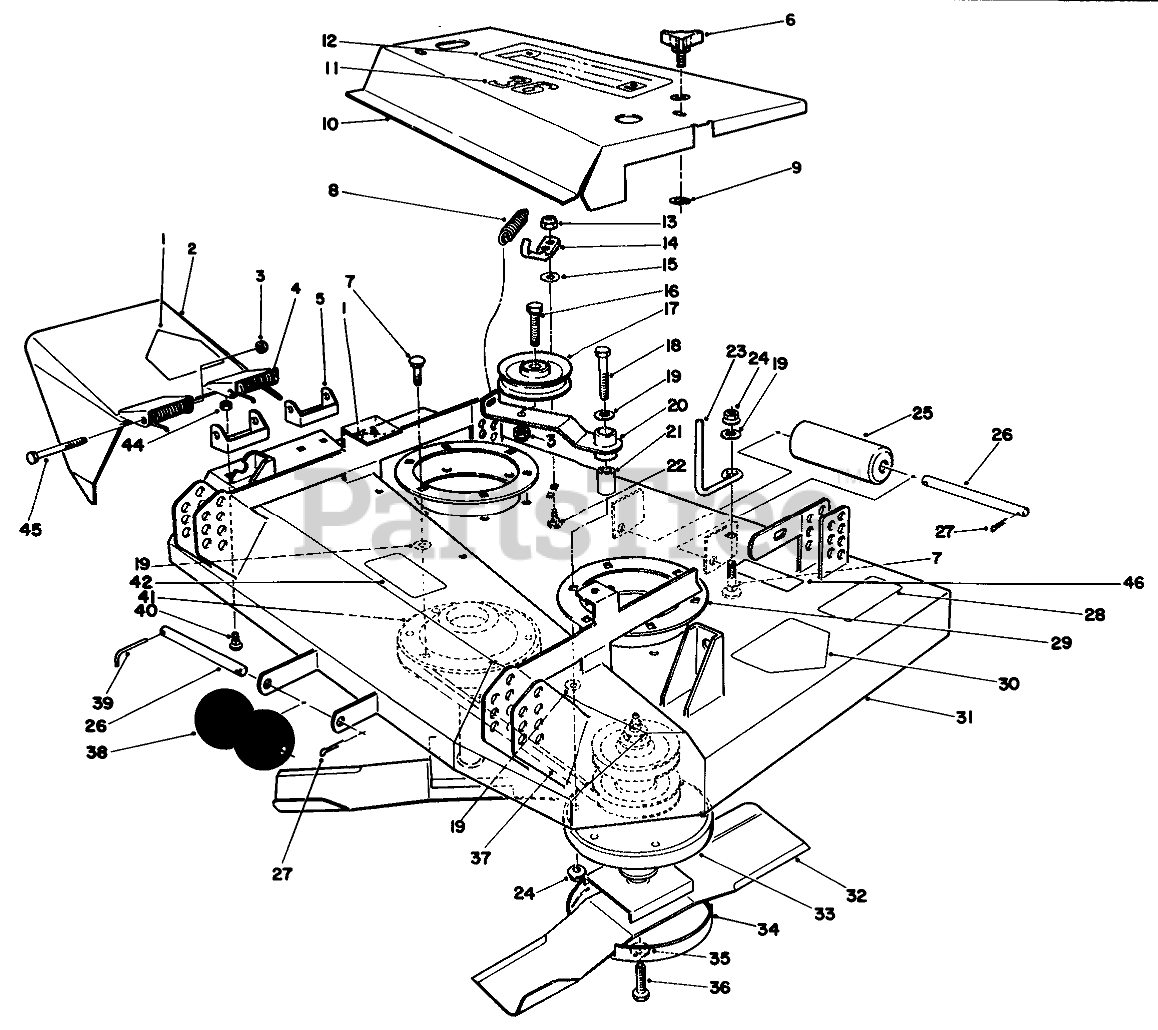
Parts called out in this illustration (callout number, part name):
1	DECAL-DANGER
2	Deflector-Grass (Incl. Ref. #1)
3	NUT-HEX
4	SPRING
5	Bracket-Pivot
7	SCREW-CARR
8	SPRING-EXTENSION
9	RING-RETAINING
10	Cover ASM
11	Decal-36 Inch
12	DECAL-PROLINE
13	NUT-LOCK, NI
14	ROD - SPRING
15	WASHER-FLAT
16	SCREW-HH
17	PULLEY-IDLER
18	SCREW-HH
19	WASHER-FLAT
20	Wa-Arm
21	SLEEVE-PIVOT, IDLER
22	SCREW-CARR
23	ROD-BELT
24	NUT-HF
25	ROLLER-DECK
26	SHAFT-ROLLER
27	PIN-COTTER
28	DECAL-TORQUE
29	SUPPORT-DECK, RING
30	DECAL-DANGER
31	Deck Assembly (Incl. Ref. #28, 30, 42 & 46)
32	BLADE-SAIL, EXTRA HIGH
33	HOUSING - SPINDLE ASM
34	CUP-SCALP, ANTI
35	WASHER-LOCK
36	SCREW-BLADE
37	V-BELT-DRIVE, DECK
38	ROLLER
39	PIN-SPECIAL
40	SCREW-CARR
41	SPINDLE ASM
42	DECAL-DANGER, THROWN OBJECT
44	NUT-LOCK, CONE
45	SCREW-HH
46	DECAL-DANGER
